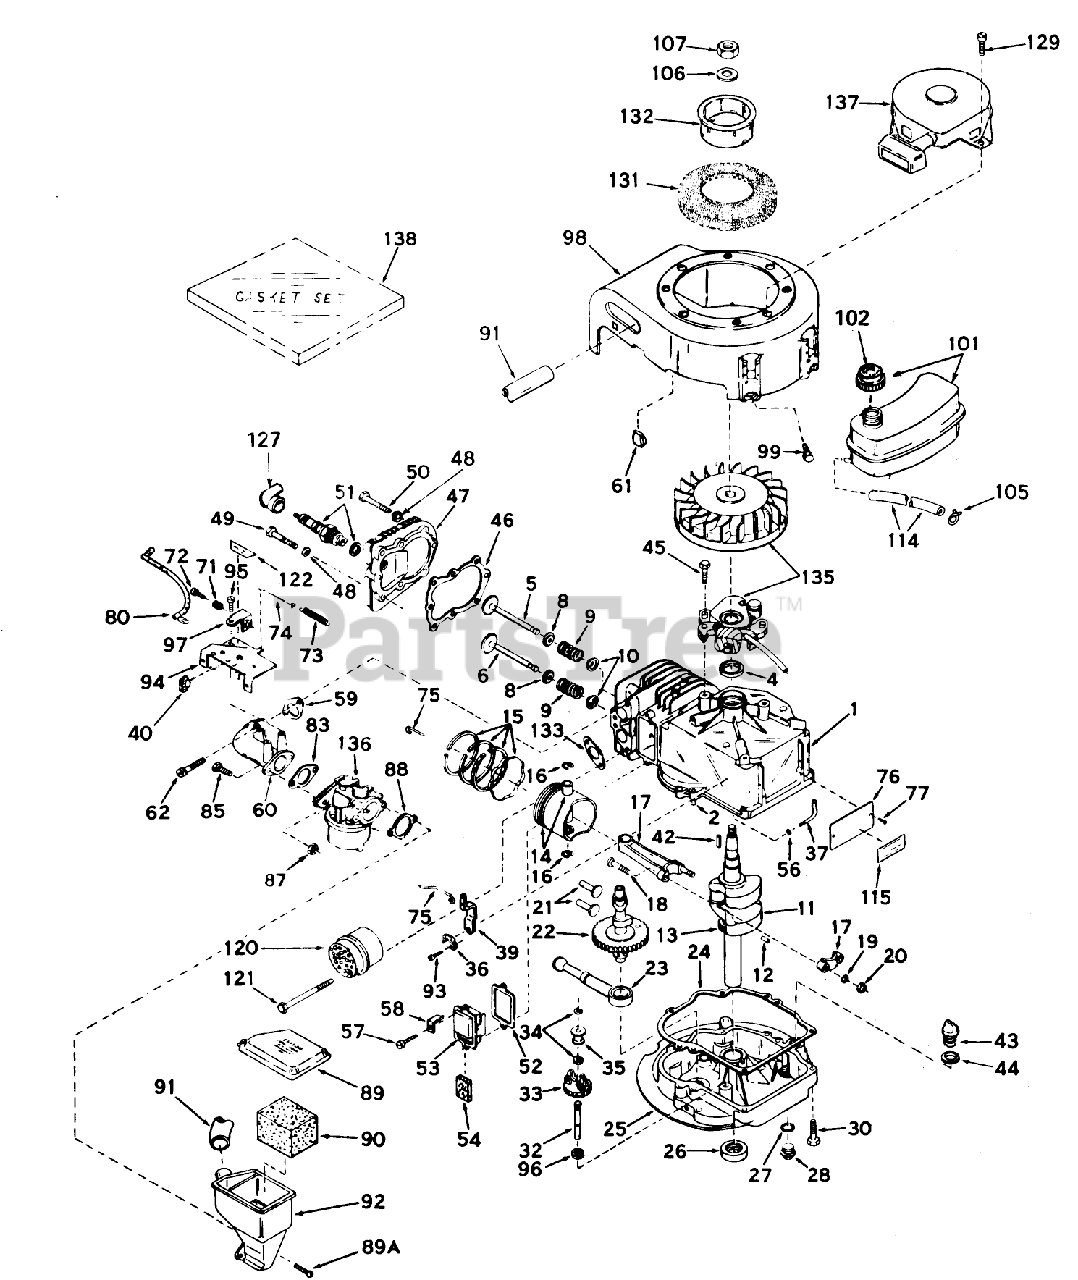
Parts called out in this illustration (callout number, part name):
1	Cylinder Assembly (Incl. Ref. #2 4)
2	Pin-Dowel
4	OIL SEAL
5	Valve, Intake (Incl. Ref. #38, 39 40) (Std.)
5	Valve, Exhaust (1/32" Overs.(Incl. Ref. 8, 9 10)
6	Valve, Exhaust (Standard)(Incl. Ref. 8, 9 10)
6	Valve, Exhaust (1/32" Overs.(Incl. Ref. 8, 9 10)
8	Cap-Upper Valve Spring
9	Spring-Valve
10	Cap-Valve, Spring
11	Crankshaft Assembly (Incl. Nos. 12 13)
12	Pin, Groove
13	Gear, Crankshaft
14	Piston Pin Assembly (Incl. 2 of No. 16) (Std.)
14	Piston Pin Assembly (Incl. 2 of No. 16) (.010 Oversize)
14	Piston Pin Assembly (Incl. 2 of No. 16) (.020 Oversize)
15	Piston Ring Set Std.
15	Piston Ring Set .010 O.S.
15	Piston Ring Set .020 O.S.
16	Ring-Retaining, Piston Pin
17	Rod Assy., Connecting (Incl. Ref. #17)
18	Bolt, Connecting
19	Washer
20	LOCKNUT
21	Lifter-Valve
22	Camshaft (Compression Release
23	Oil Pump ASM
24	Gasket, Mounting
25	Flange Assembly, Mounting (Incl. Nos. 26, 27, 28 32)
26	Seal Oil
27	Gasket-Oil Drain
28	Plug Oil Drain
30	Screw (1/4-20 x 1-1/4)
32	Shaft-Governor
33	Governor Gear ASM
34	Ring-Retaining
35	Spool-Governor
36	Clamp-Lever, Governor
37	Rod, Governor (Incl. No. 36)
39	Governor Lever
40	Knob-Control
42	Key Flywheel
43	Plug-Fill, Oil
44	Gasket
45	Screw
46	Gasket-Cylinder Head
47	CYLINDER HEAD
48	Washer
49	Screw
50	Screw Hex Hd. Cap
51	Plug, Spark (J17LM or equiv.)
52	Gasket Breather
53	Breather Assembly (Incl. Nos. 52 84)
54	Element-Breather
56	Washer-Flat
57	Screw
58	Retainer Clip
59	Gasket, Intake
60	Pipe, Intake
61	51004 GIL ROTARY TI
62	Screw (1/4-20 x 1)
71	Spring
72	Screw, Hex Hd.
73	Spring, Governor
74	Link Governor Spring
75	Link Governor
76	IDENTIFICATION PLATE
77	Stud
80	Wire, Ground
83	Gasket
87	Nut and Lock Washer (1/4-28)
88	Gasket-Air Cleaner
89	Cover, Air Cleaner
89A	Screw, Fil. Hd. Sems
90	Element, Air Cleaner
91	Tube, Air Cleaner
92	Body, Air Cleaner
93	Screw
94	Control Assy., Speed
95	Screw (10-24 x 9/16)
96	Washer-Flat
97	Brachet, Control
98	Housing, Blower
99	Screw (1/4-20x19/32)
101	Tank, Fuel
102	Cap, Fuel
105	Clamp-Line, Fuel
106	Washer
107	Hex Nut
114	Line-Fuel (8.62)
115	480B GIL SNWTHWR O/
120	Muffler Kit (Incl. Ref. #72)
121	Screw, Hex hd. cap
122	Decal
127	Cover-Spark Plug
129	Screw
131	Screen, Air
132	Starter Cup
133	Gasket-Intake
135	Magneto
136	Carburetor
137	Starter, Rewind
138	Gasket Set
